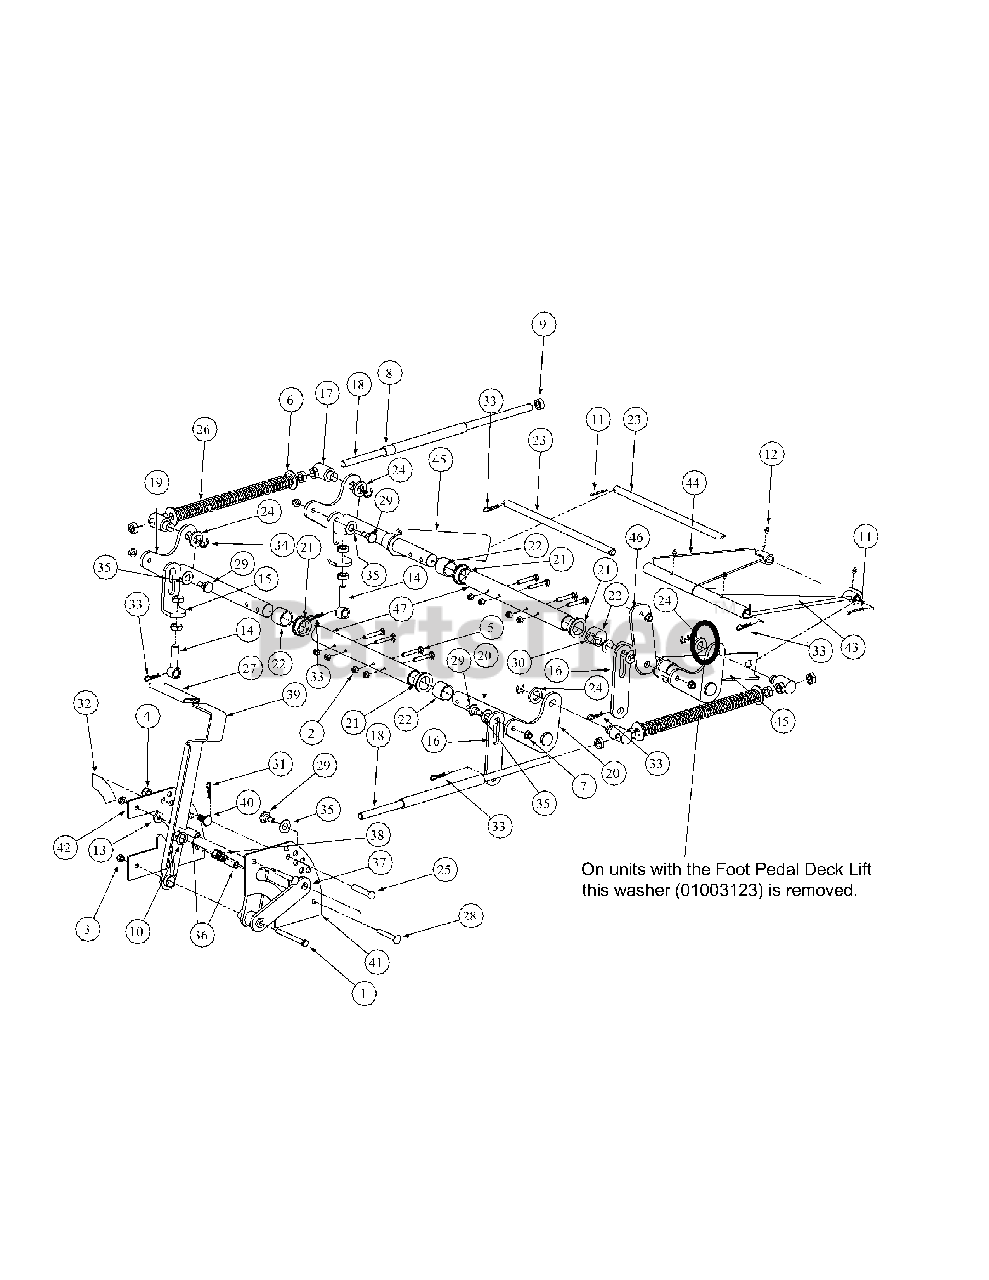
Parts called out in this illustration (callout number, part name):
1	Hex Cap Screw, 3/8-16, 3.75
2	Nut, 5/16-18, Nylock
3	Nylock Insert Lock Nut, 3/8-16
4	Nylock Insert Lock Nut, 1/2-13
5	Hex Cap Screw, 5/16-18 x 2
6	Flat Washer, 5/8
7	Hex Nut, Flange Lock, 3/8-16
8	PVC Hose, 5/8
9	Jam Nut, 5/8-11
10	Flat Washer, .06, .776, 1.25
11	Cotter Pin, 3/16 x 1-1
12	Grease Fitting, 1/4-28 x 3/16
13	Idler Washer
14	Eye Bolt, 5/8ID
15	Eye Bolt Mount Link, 5/8 ID
16	Deck Link
17	Ferule Lift
18	Lift Connector Rod
19	Bellecrank Weldment Lift, Left Hand
20	Bellecrank Weldment Lift, Right Hand
21	Hex Flange Bearing, 1.25 ID
22	Frame Lift Spacer
23	Front Lift Link, Rod Mount
24	Spacer, .812 ID x .268 Lg.
25	Clevis Pin, .500 Dia. x 2.625 Lg.
26	Lift Compression Spring
27	Lift Handle Grip
28	Carriage Bolt, 3/8-16, 2.75
29	Shoulder Screw, 0.625 OD x .437 Lg.
30	Shoulder Screw, 0.625 OD x .830 Lg.
31	Cotter Pin, .148 x 3.00
32	Decal Height Indicator
33	Cotter Pin
34	E Clip, 3/4 Dia.
35	Nylon Flat Washer, 5/8
36	Spacer, .39 ID x .63 OD x 1.442
37	Lift Pivot Assembly
38	Lift Handle Spring
39	Lift Handle Assembly
40	Shoulder Screw, 5/8 OD x 0.264
41	Outer Lift Index Plate
42	Inner Lift Index Plate
43	Bearing Lift Brace Assembly, Right Hand
44	Bearing Lift Brace Assembly, Left Hand
45	Front Frame Strut Assembly
46	Lift Link Adjustment
47	Lift Shaft Holder
